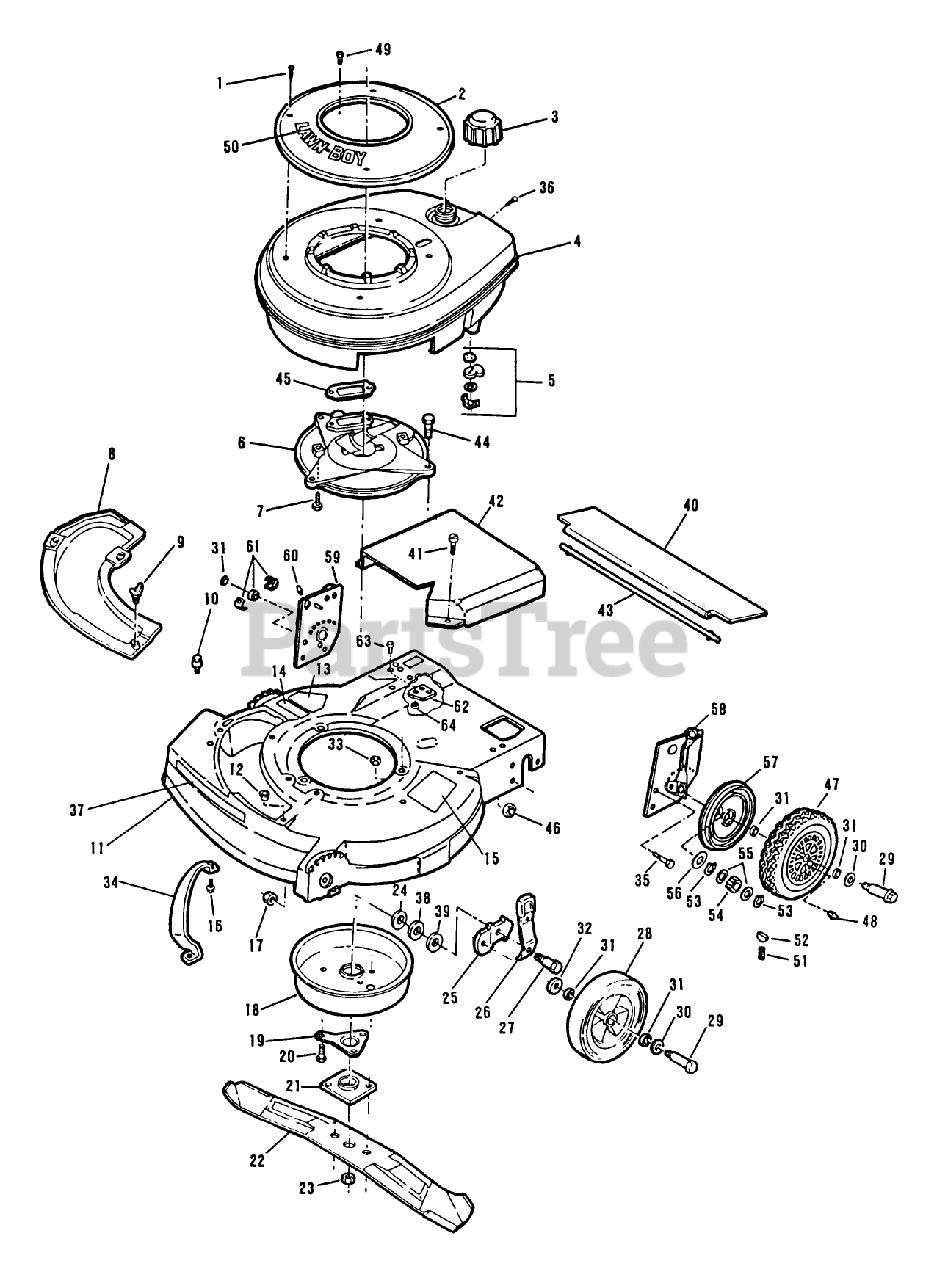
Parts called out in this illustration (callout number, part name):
1	SCREW - SELF TAPPING
3	FUEL CAP & INSERT
5	SHUT OFF VALVE KIT
6	PLATE F
7	SCREW V
9	WING SCREW LAWRE
15	PAD FOOT
18	MUFFLER COVER F
19	SUPPORT F
20	SCREW
21	PLATE AND COLLAR ASM
23	NUT-BLADE
24	WASHER
26	SPRING ARM ASM
27	BOLT
29	BOLT WHEEL
30	SPACER
31	WASHER
32	WASHER WROUGHT
33	NUT-LOCK F
34	BAR-TOE
36	SCREW S
38	WASHER
39	WASHER
44	SCREW-HH
46	NUT-LOCK F
48	FITTING LINCOLN
49	SCREW SEMS SM
51	SPRING
52	KEY
53	RET RING
54	PINION BROCKWAY
55	SPACER/GR ALGHNY
60	REAR AXLE BEARING
61	**FITTING LINCOLN
63	BOLSTER
64	LOCKNUT E
